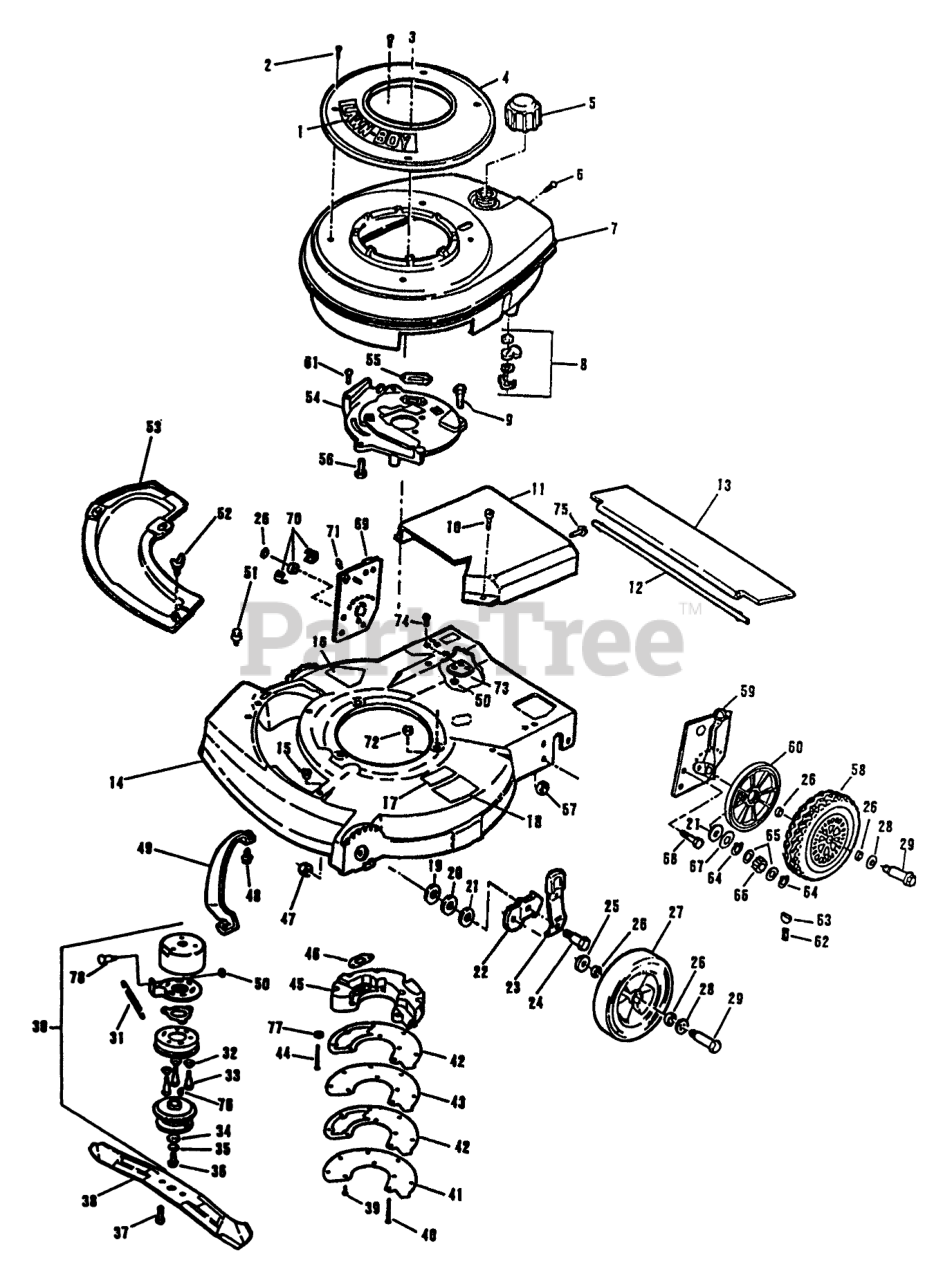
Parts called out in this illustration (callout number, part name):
1	APPLIQUE
2	SCREW S
3	SCREW SEMS SM
4	STARTER BASE&NUTB
5	FUEL CAP & INSERT
6	SCREW S
7	Shroud-Engine
8	SHUT OFF VALVE KIT
9	SCREW-HH
10	SCREW SEMS TRM HEX HD
11	COVER DRIVE PL
12	ROD-TRAILING SHIELD
13	SHIELD-TRAILING
14	Housing
15	Grommet
16	Decal
17	DECAL
18	PAD FOOT
19	WASHER
20	WASHER
21	WASHER
22	Bracket
23	SPRING ARM ASM
24	BOLT
25	WASHER WROUGHT
26	WASHER
27	WHEEL&TIRE 6"
28	WASHER-PLAIN
29	BOLT WHEEL
30	CLUTCH BRAKE AY S
31	SPRING
32	SPRING
33	SCREW,SHOULDER SM
34	WASHER
35	LOCKWASHER
36	SCREW-SOCKET HEAD
37	SCREW SEMS
38	21" Blade
39	SCREW
40	Screw
41	COVER MUFFLER F
42	GASKET F
43	SHIELD F
44	Screw
45	Muffler
46	GASKET F
47	NUT
48	Screw
49	BAR-TOE
50	LOCKNUT E
51	Bolt
52	WING SCREW LAWRE
53	CoverPlate
54	PLATE S
55	Gasket
56	SCREW V
57	NUT-LOCK F
58	Rear Wheel
59	HEIGHT ADJ AY-LH
60	W/COVER WHITE PL
61	SCREW-HH
62	SPRING
63	KEY
64	RET RING
65	SPACER/GR ALGHNY
66	PINION BROCKWAY
67	THRUST WASHER
68	Screw
69	HEIGHT ADJ AY-RH
70	REAR AXLE BEARING
71	FITTING LINCOLN
72	NUT-LOCK F
73	BOLSTER
74	Screw
75	SCREW
76	KEY
77	WASHER F
78	BOLT
